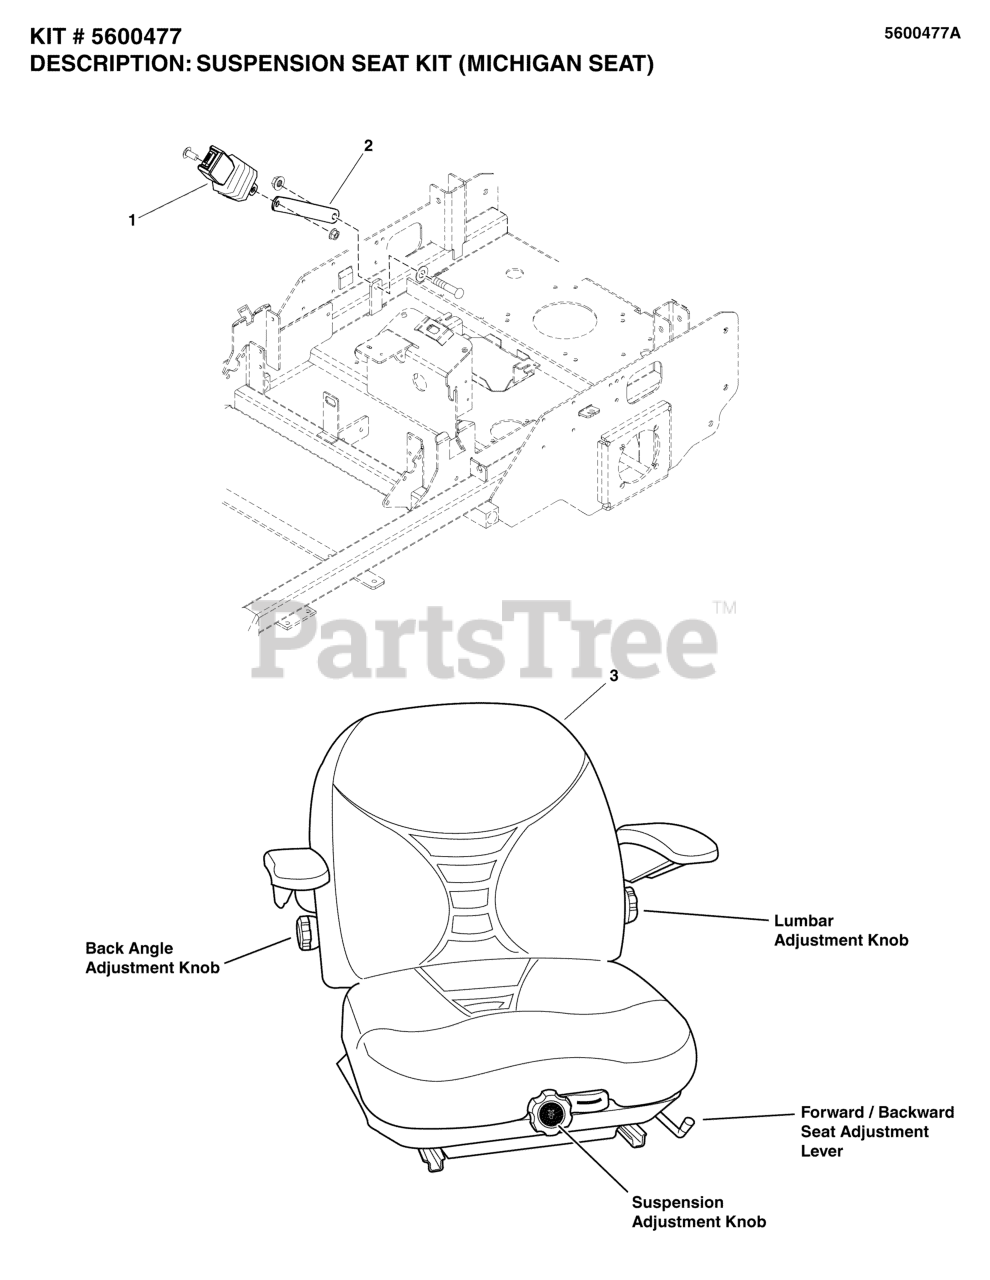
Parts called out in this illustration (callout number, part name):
1	SEAT BELT ASSM, RETRACTOR + SUP SLEEVE
2	EXTENSION, SEAT BELT - BLK
3	SEAT,SUSP.TYPE,MICHIGAN SEAT, V5300, BLK
